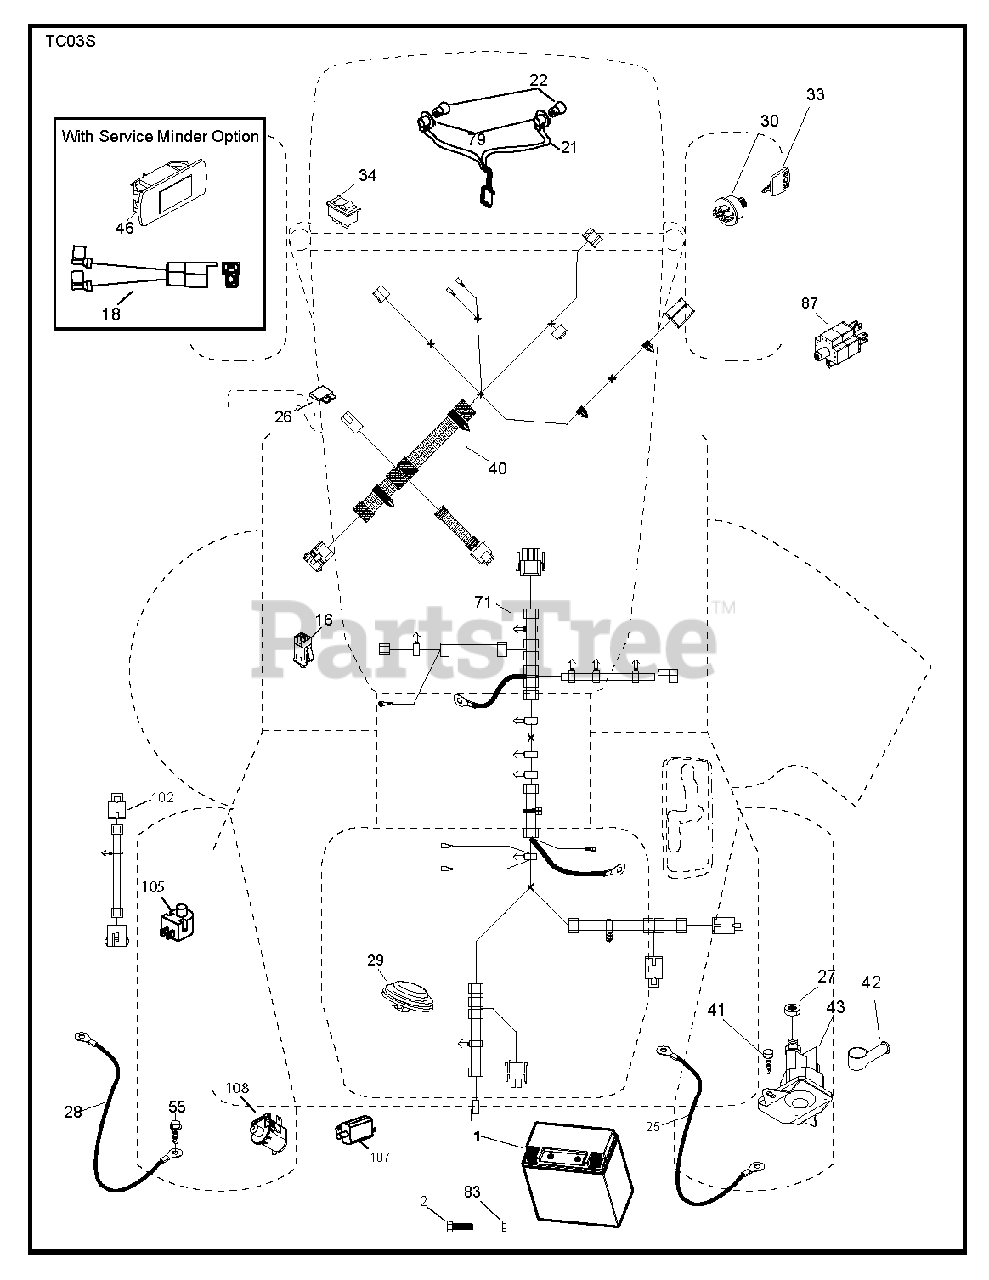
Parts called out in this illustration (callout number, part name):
16	SWITCH INTERLOOK PUSH-IN
21	HARNESS ASSY LIGHT
22	LIGHTBULB
26	FUSE 20AMP
27	NUT
29	SWITCH.SEAT.DELTA.OPC.
30	SWITCH.IGN.DELTA.W.LGH.ROS
33	KEY.CHAIN.BLISTER.PACK.GEN.INT
34	SWITCH LT
41	SCREW
42	TERMINAL COVER
43	SOLENOID.W/BRASS.PLUNG
46	GUAGE.SRVCMNDR.HRMTR.
55	SCREW 5/16"
79	BULB HOLDER ASM.
105	REVERSE SWITCH
108	SWITCH.SNAPMOUNT.NC
